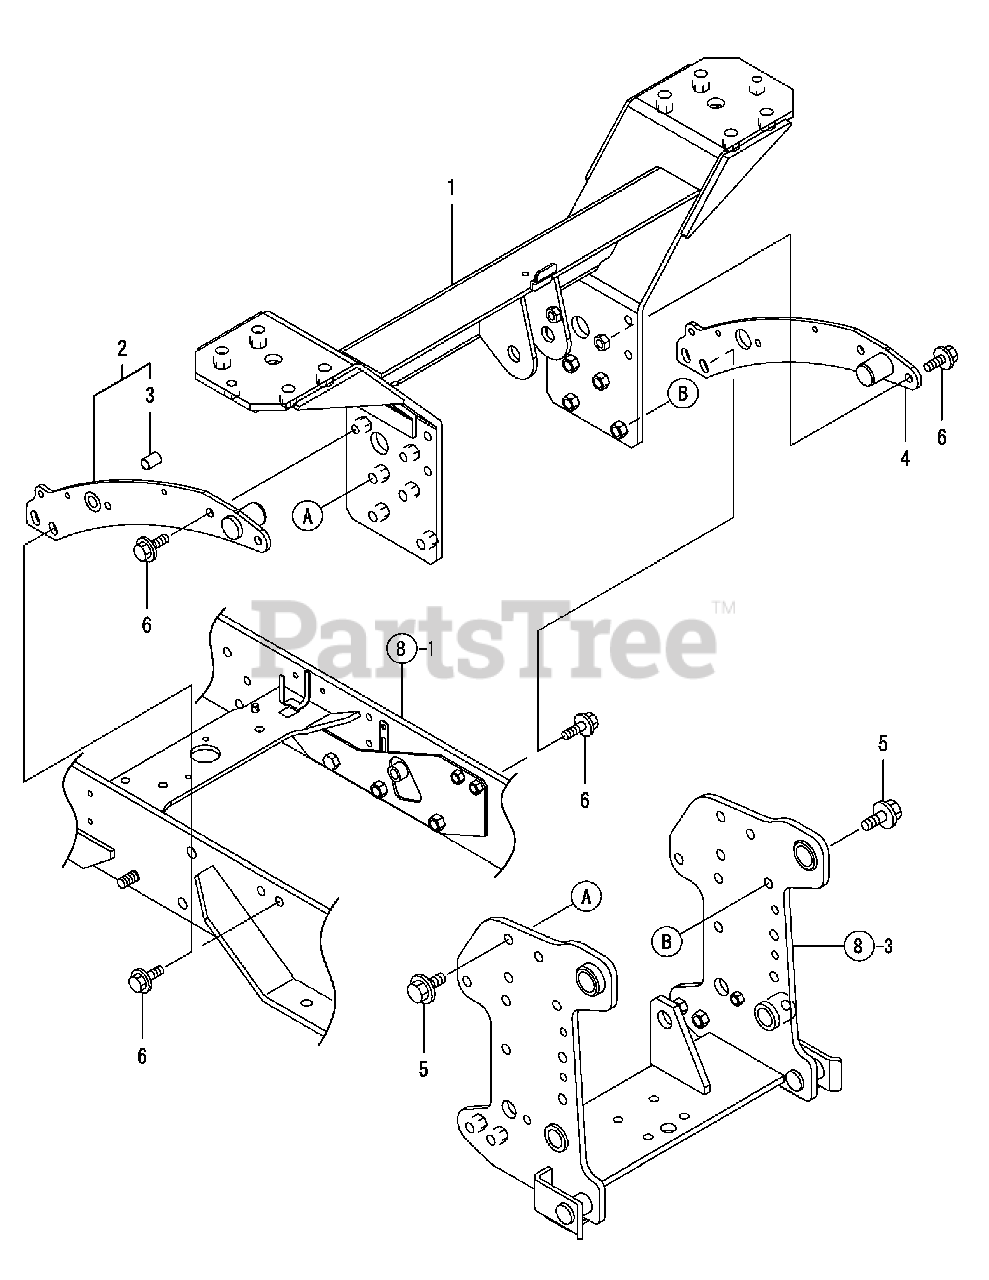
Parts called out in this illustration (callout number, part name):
1	FRAME ASSY, LOWER
2	PLATE ASSY, SIDE L
4	PLATE ASSY, SIDE R
6	BOLT M10X 30 PLATED
